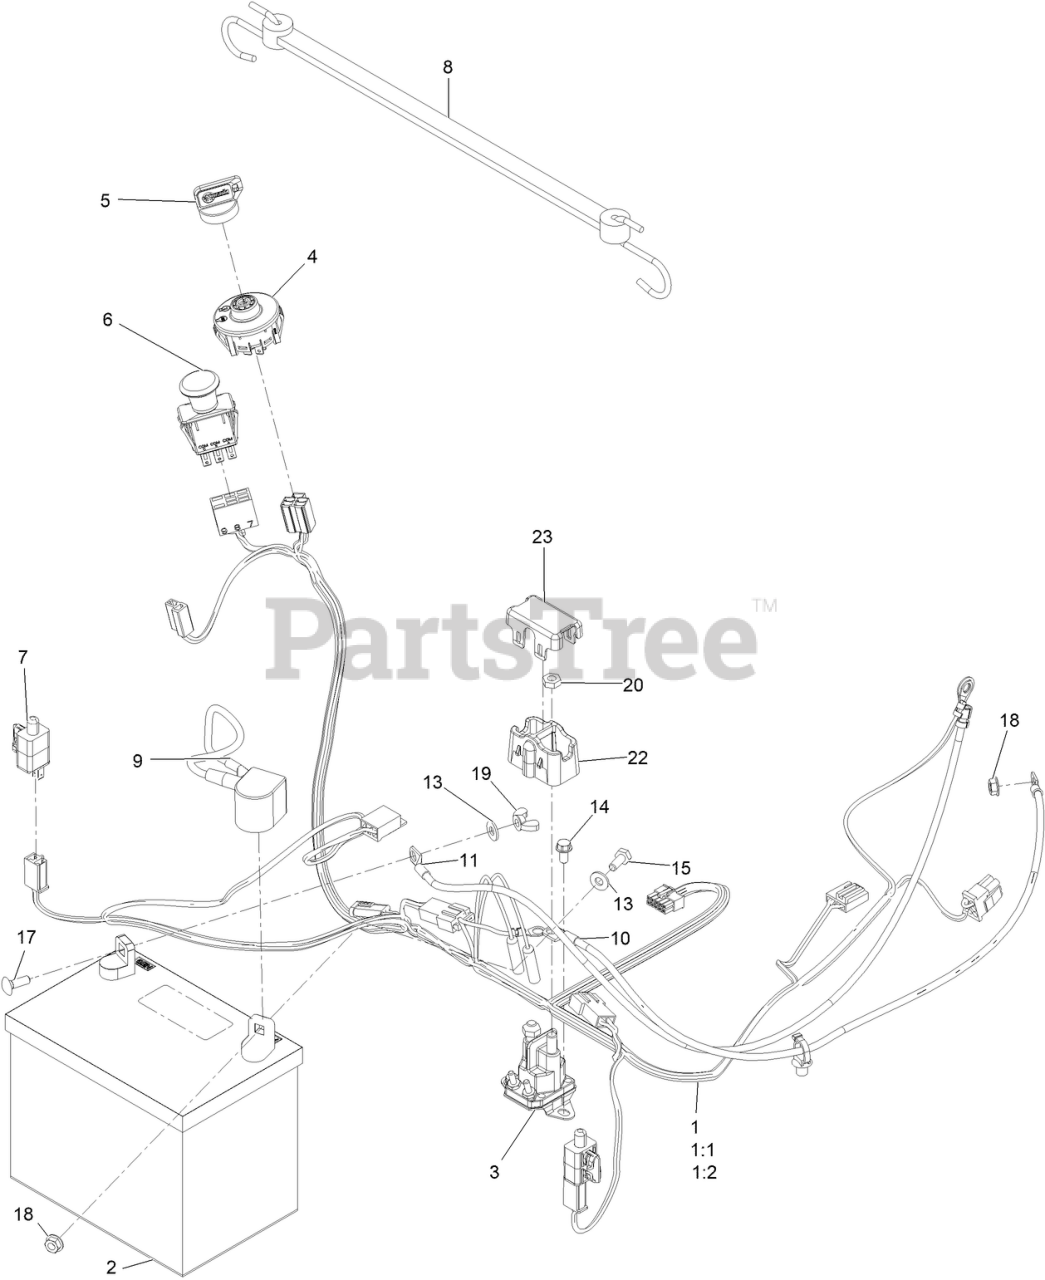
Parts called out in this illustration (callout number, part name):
1	HARNESS-WIRE
2	BATTERY
3	SOLENOID
4	SWITCH-IGNITION
5	KEY-IGNITION
6	SWITCH-PTO
8	STRAP-RUBBER
9	CABLE-BATTERY, POS
10	CABLE-BATTERY, RED (8 GAUGE)
11	CABLE-BATTERY, BLACK
13	WASHER-FLAT
14	SCREW-HWH
15	SCREW-HH
17	BOLT-CARR
19	NUT-WING
20	NUT-JAM
22	COVER-SOLENOID
23	CAP-SOLENOID
